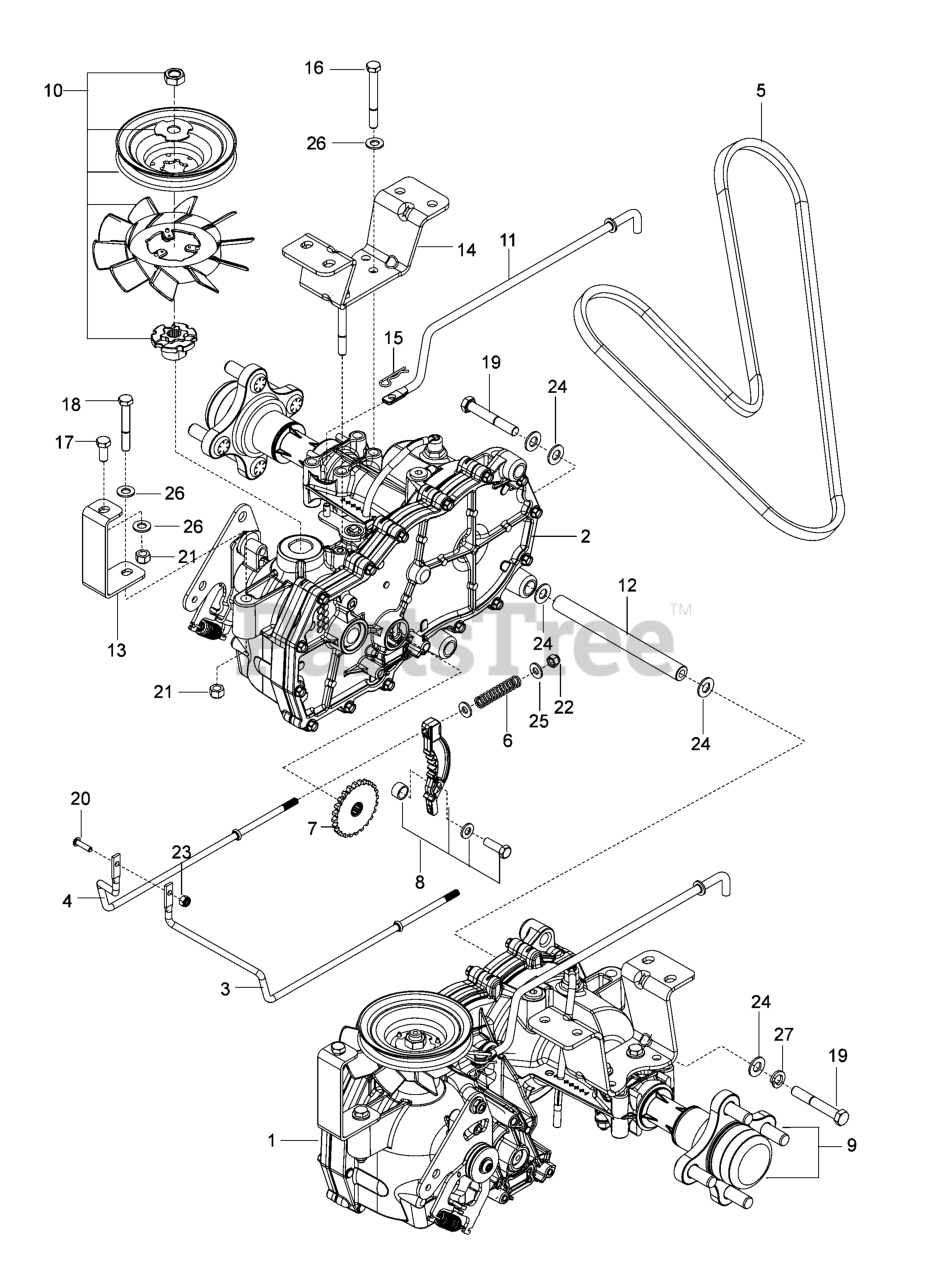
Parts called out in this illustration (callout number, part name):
1	TRANSAXLE, Hydro Gear, LH
2	TRANSAXLE, Hydro Gear, RH
3	ROD, Brake, Left
4	ROD, Brake, Right
6	SPRING, Brake
7	GEAR, Brake
8	ARM, Brake
10	KIT, Pulley, Fan
11	ROD, Bypass
13	SUPPORT, Transaxle, Front
14	SUPPORT, Transaxle, Rear
15	PIN, Retainer
16	CAPSCREW, 5/16-18 X 2-3/4 HEX HEAD
17	CAPSCREW, 5/16-18 X 3/4 GR. 5 ZD
18	CAPSCREW, 5/16-18 X 2-1/4 HEX HD
19	CAPSCREW, 3/8-16 X 2-1/2
20	SCREW, 10-24 X 3/4 SLOTTED ROUND HD
21	Nut, Lock 5/16-18 unc
22	LOCKNUT, 1/4-20 HEX NYLOC
23	LOCKNUT, 10-24 HEX NYLOC
24	Washer 13/32 x 13/16 x 16 Ga.
25	WASHER, Flat, 1/4 SAE
26	WASHER, 11/32 x 11/16 x 16 Ga.
27	WASHER, 3/8, SLW ZD
